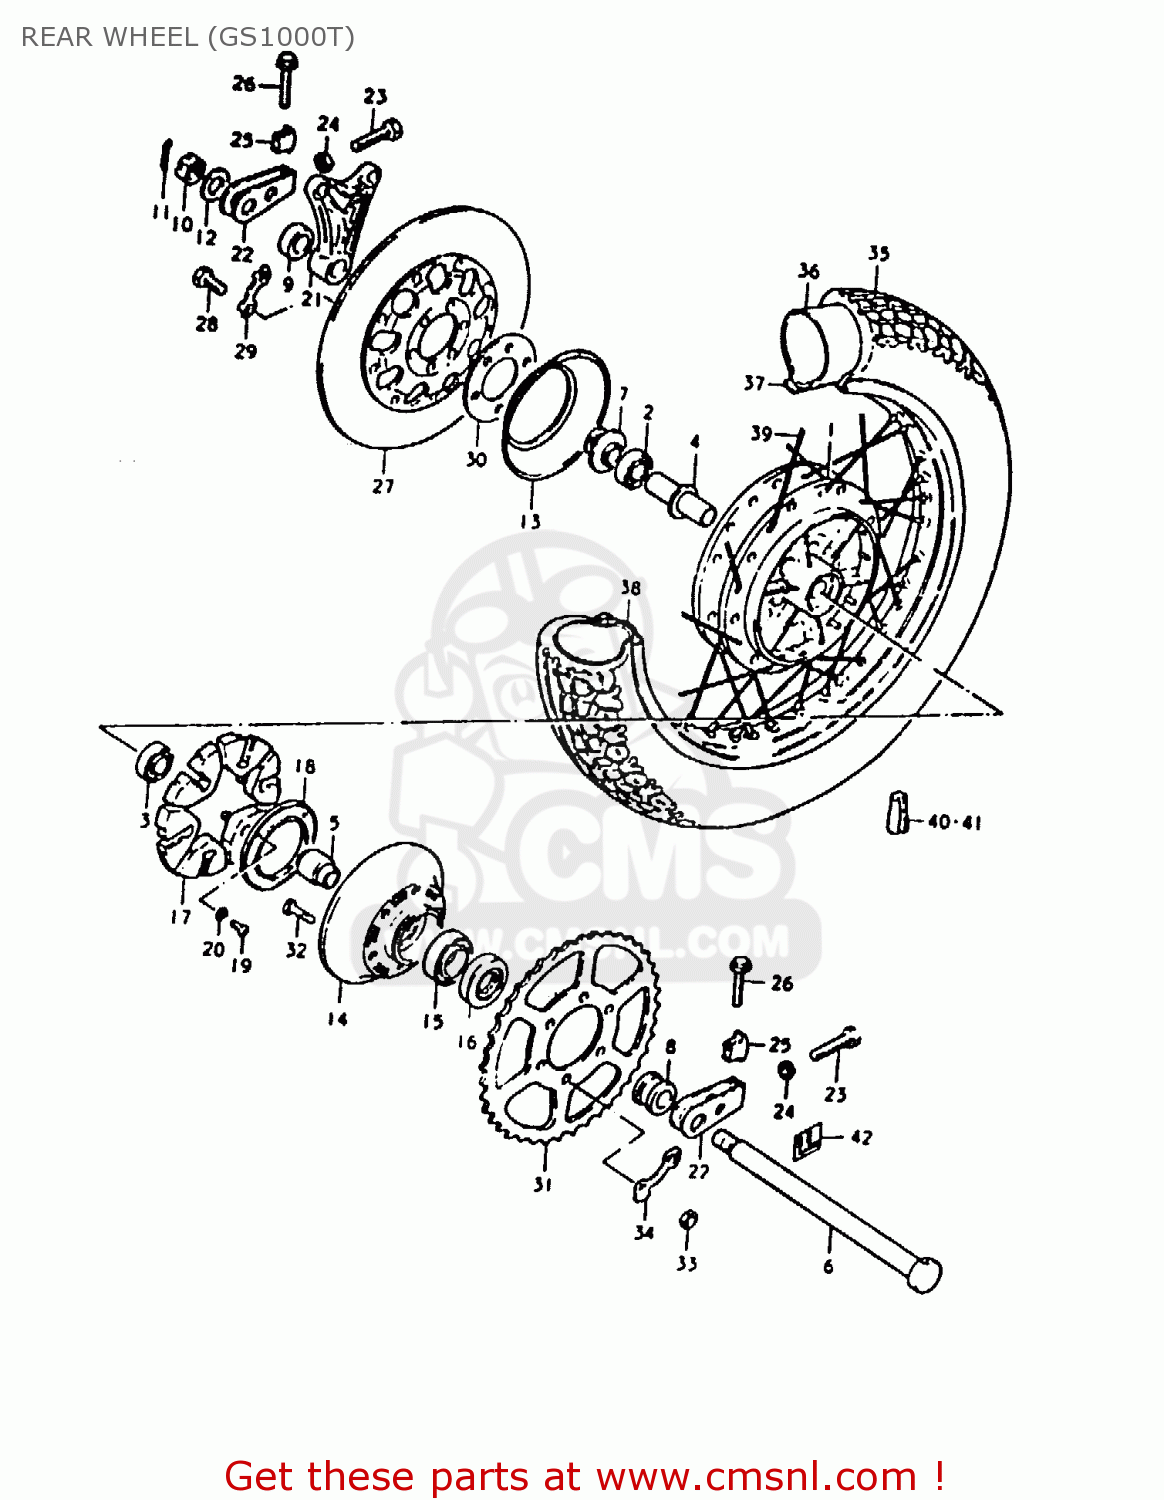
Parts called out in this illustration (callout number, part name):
1	DRUM,REAR HUB
2	BEARING
3	BEARING, LH
4	SPACER,REAR HUB BEARING
5	SPACER,REAR HUB BEARING
6	AXLE,REAR
7	SPACER,REAR AXLE,RIGHT
8	SPACER(20X33X28.3)
9	SPACER(20X38X12)
10	NUT 18MM
11	PIN,COTTER
12	WASHER(19X34X4)
13	COVER,REAR WHEEL HUB
14	DRUM,REAR SPROCKET MOUNT
15	BEARING
16	SEAL,OIL(33X62X7)
17	ABSORBER,REAR HUB SHOCK
18	PLATE,REAR HUB SHOCK ABSORBER
19	SCREW
20	LOCK WASHER
21	BRACKET,RR,CALIPER
22	ADJUSTER,CHAIN
23	BOLT
24	NUT
25	SUPPORTER,CHAIN ADJUST
26	BOLT (8X40)
27	DISC,RR BRAKE
28	BOLT 8X40
29	WASHER
30	SHIM,BRAKE DISC
31	SPROCKET,REAR
32	BOLT
33	NUT
34	WASHER
35	TIRE
36	TUBE ASSEMBLY,WHEEL,INNER
37	PROTECTOR,INNER TUBE
38	RIM (N17X7T2.50)
39	SPOKE SET
40	BALANCER,WHEEL (B)
41	BALANCER,WHEEL (30G)
42	LABEL,CHAIN WEAR INDICATOR
